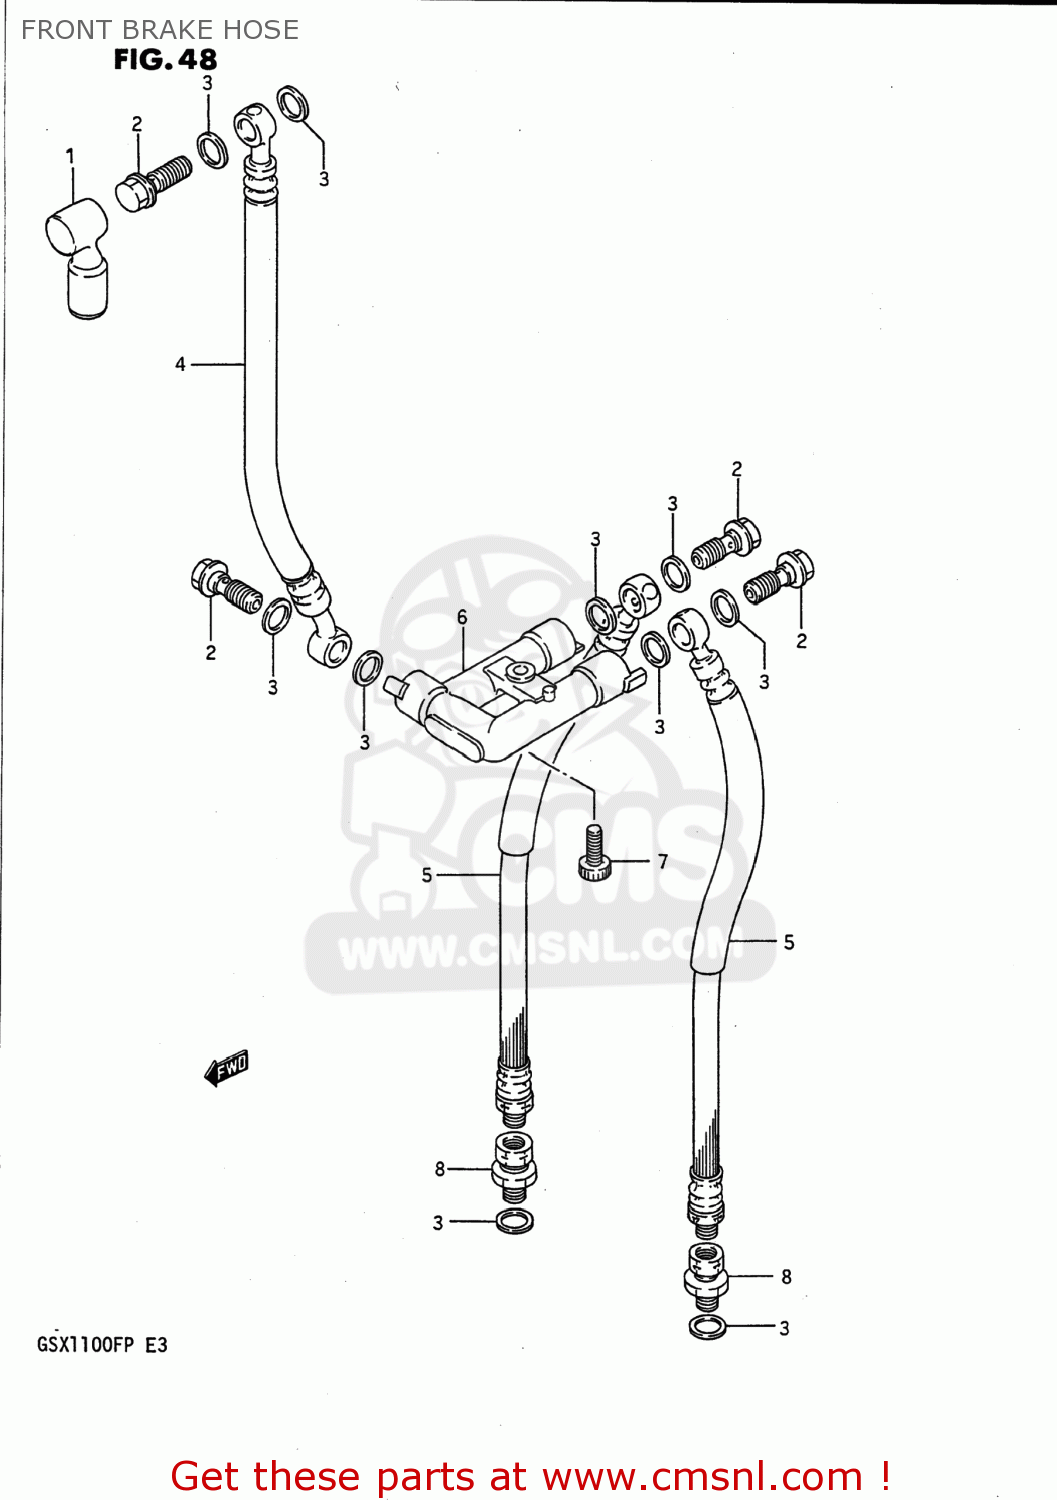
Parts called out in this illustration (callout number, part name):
1	BOOT,MASTER CYLINDER
2	BOLT UNION
3	WASHER(10X15X1.5)
4	HOSE,FRONT BRAKE
5	HOSE COMP,FRONT BRAKE
6	JOINT,BRAKE HOSE
7	BOLT
8	ADAPTER,BRAKE HOSE
